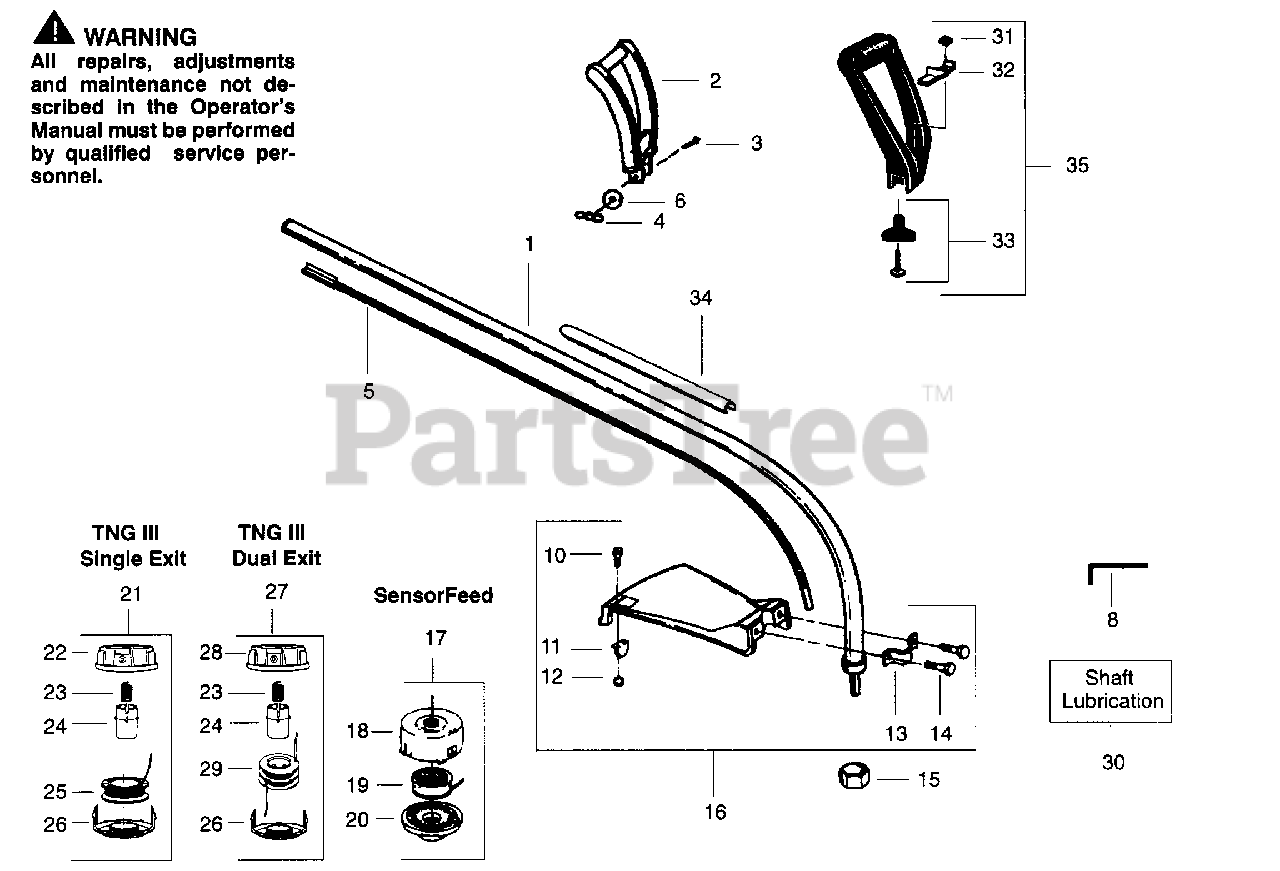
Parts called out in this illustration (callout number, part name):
1	Drive Shaft Housing, Models GTI 16 & GTI 16 SUPER
1	Drive Shaft Housing, Model GTI 17LE
1	Drive Shaft Housing Model GTI 16D
2	Handle Ass'y.Model GTI 16 Type 1 & 2
4	Wing Nut
5	Drive Shaft, Models GTI 16, GTI 16 SUPER & GTI 16D
5	Drive Shaft, Model GTI 17LE
8	Hex Wrench (5/32")
11	Line Limiter
12	Nut
15	Dust Cup
16	Shield Kit Ass'y. (Incl. 10-12 & 14) Models GTI 16, GTI 16 SUPER & GTI 16D
16	Shield Kit Ass'y. (Incl. 10-12 & 14) Model GTI 17LE
17	Cutting Head Ass'y, (incl. 18-20) Model GTI 16 SUPER
18	Hub Ass'y, Model GTI 16 SUPER
19	Spool w/Line, Model GTI 16 SUPER
20	Cover, Model GTI 16 SUPER
21	Cutting Head Ass'y, (Incl. 22-26) Models GTI 16 & GTI 17LE
22	Hub Ass'y, Models GTI 16 & GTI 17LE
23	Spring, Models GTI 16,GTI 16D & GTI 17LE
24	Release Button, Models GTI 16,GTI 16D, GTI 17LE
25	Spool w/Line, Models GTI 16 & GTI 17LE
26	Cover, Models GTI 16,GTI 16D & GTI 17LE
27	Dual Line Cutting Head, Model GTI 16D (Incl. 23,24,26,28,&29)
28	Hub Ass'y, Model GTI 16D
29	Dual Spool w/Line, Model GTI 16D
30	Shaft Lubrication
33	"T" Handle Kit
34	Decal- Drive Shaft, Models GTI 16, GTI 17LE & GTI 16 SUPER
34	Decal- Drive Shaft, Model GTI 16D
35	Cushioned Assist Handle Kit, GTI 16 SUPER, GTI 17LE, GTI 16D & GTI 16 Type 3
